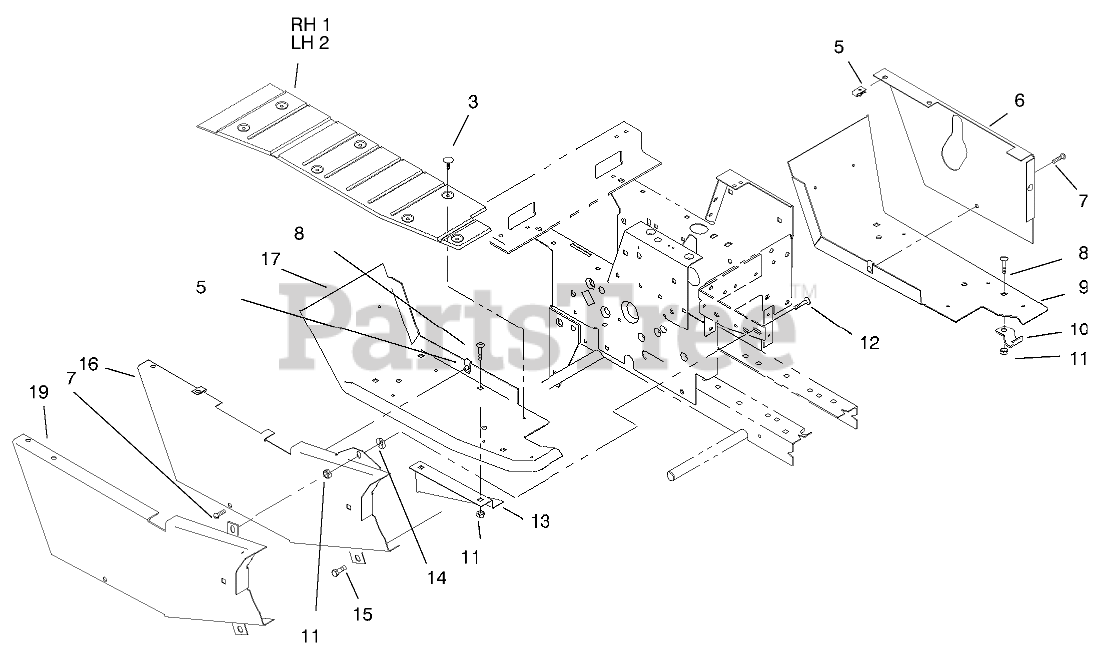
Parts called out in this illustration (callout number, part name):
1	PAD-FOOT RH
2	PAD-FOOT LH
3	FASTENER-PANEL
6	COVER-LH
7	SCREW-PPH
8	BOLT-CARR
9	FOOTREST-LH
10	BRACKET
11	NUT-LOCK, NI
12	BOLT-CARR
13	GUIDE-LOWER BELT
14	NUT-PUSH
15	Bolt
17	FOOTREST-RH
19	Belt Guard
